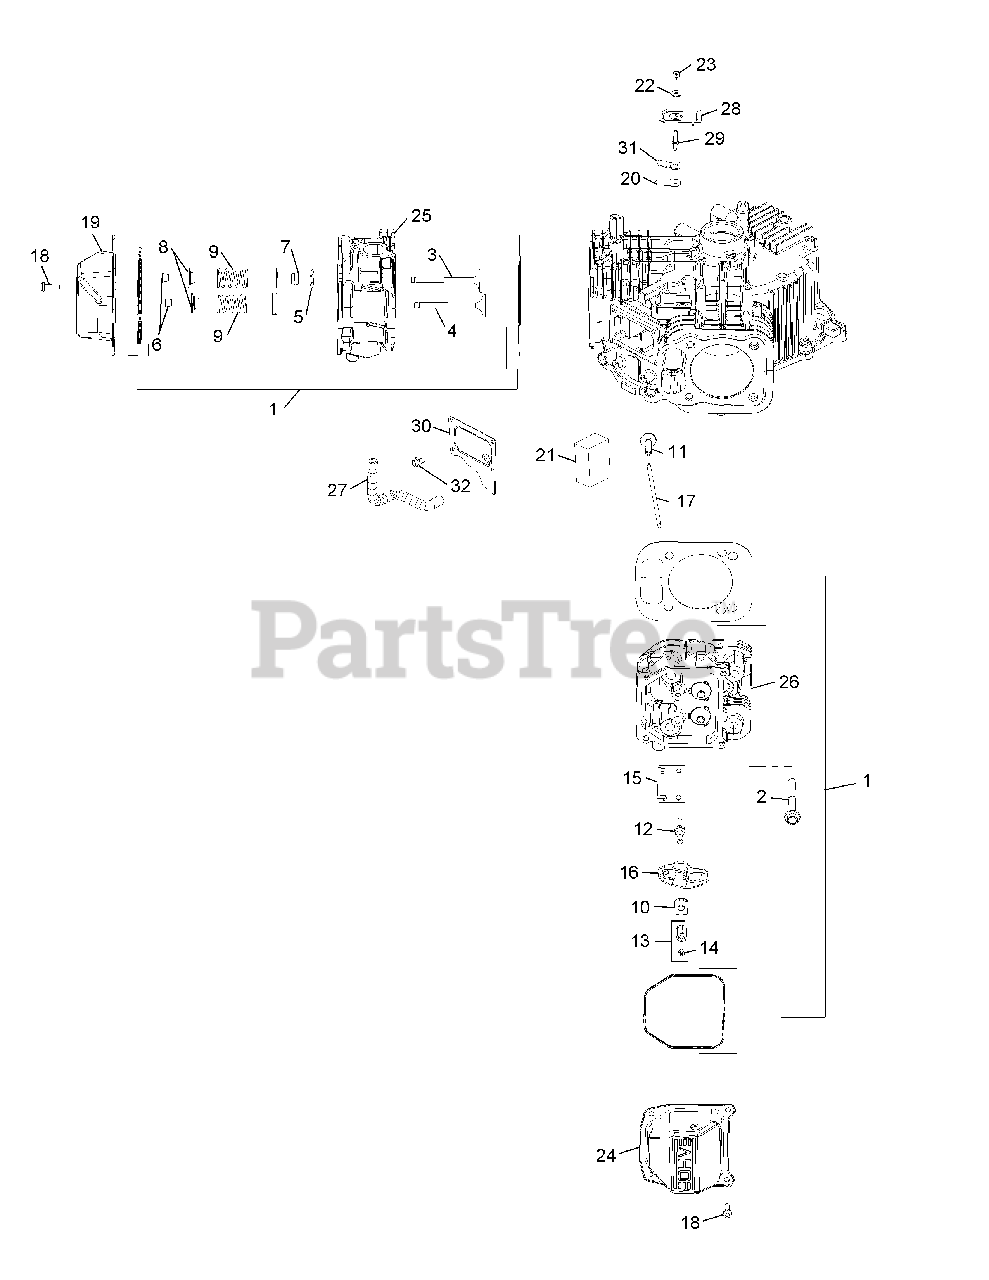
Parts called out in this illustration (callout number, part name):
1	Cylinder Head Gasket Kit
2	Flange Screw, M10 x 1.5 x 90
4	Exhaust Valve
5	Spacer (.010")
6	Retainer Kit
7	Valve Band Seal
8	Valve Spring Cap
9	Valve Spring
10	Rocker Arm Pivot
13	Hex Nut Assembly (Inc. #14)
18	Pan Head Screw
20	Breather Reed
21	Breather Filter
22	Sealing Washer
23	Lock Nut, M5 x 8
24	Rocker Cover
25	Cylinder Head Assembly Kit, #1
26	Cylinder Head Assembly Kit, #2
27	Breather Hose
28	Breather Cover
30	Breather Media Cover
31	Reed Retainer
32	Thread Forming Screw
